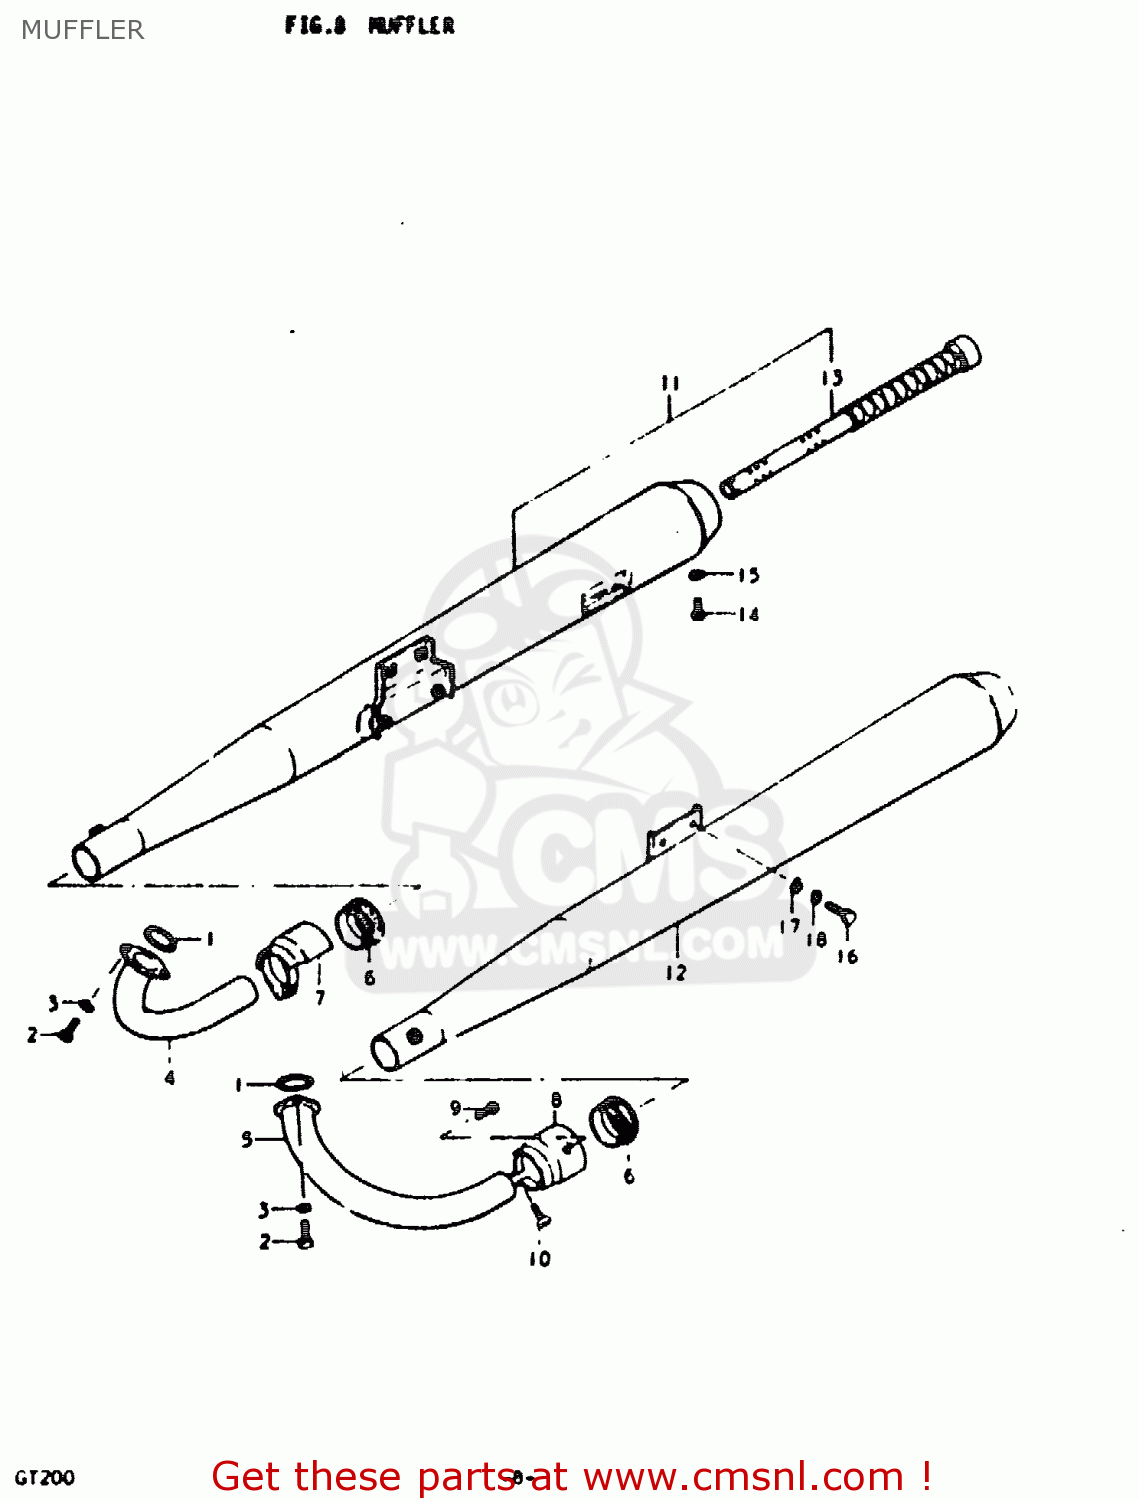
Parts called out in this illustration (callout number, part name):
1	GASKET,EXHAUST PIPE (NAS)
2	BOLT
3	LOCK WASHER
4	PIPE, EXHAUST RH
5	PIPE, EXHAUST LH
6	CONNECTOR,MUFFLER
7	COVER, RH
8	COVER, LH
9	SCREW
10	SCREW
11	MUFFLER ASSY, RH
12	MUFFLER ASSY, LH
13	PIPE,BAFFLE
14	BOLT(5X8)
15	LOCK WASHER
16	BOLT
17	WASHER
18	LOCK WASHER
